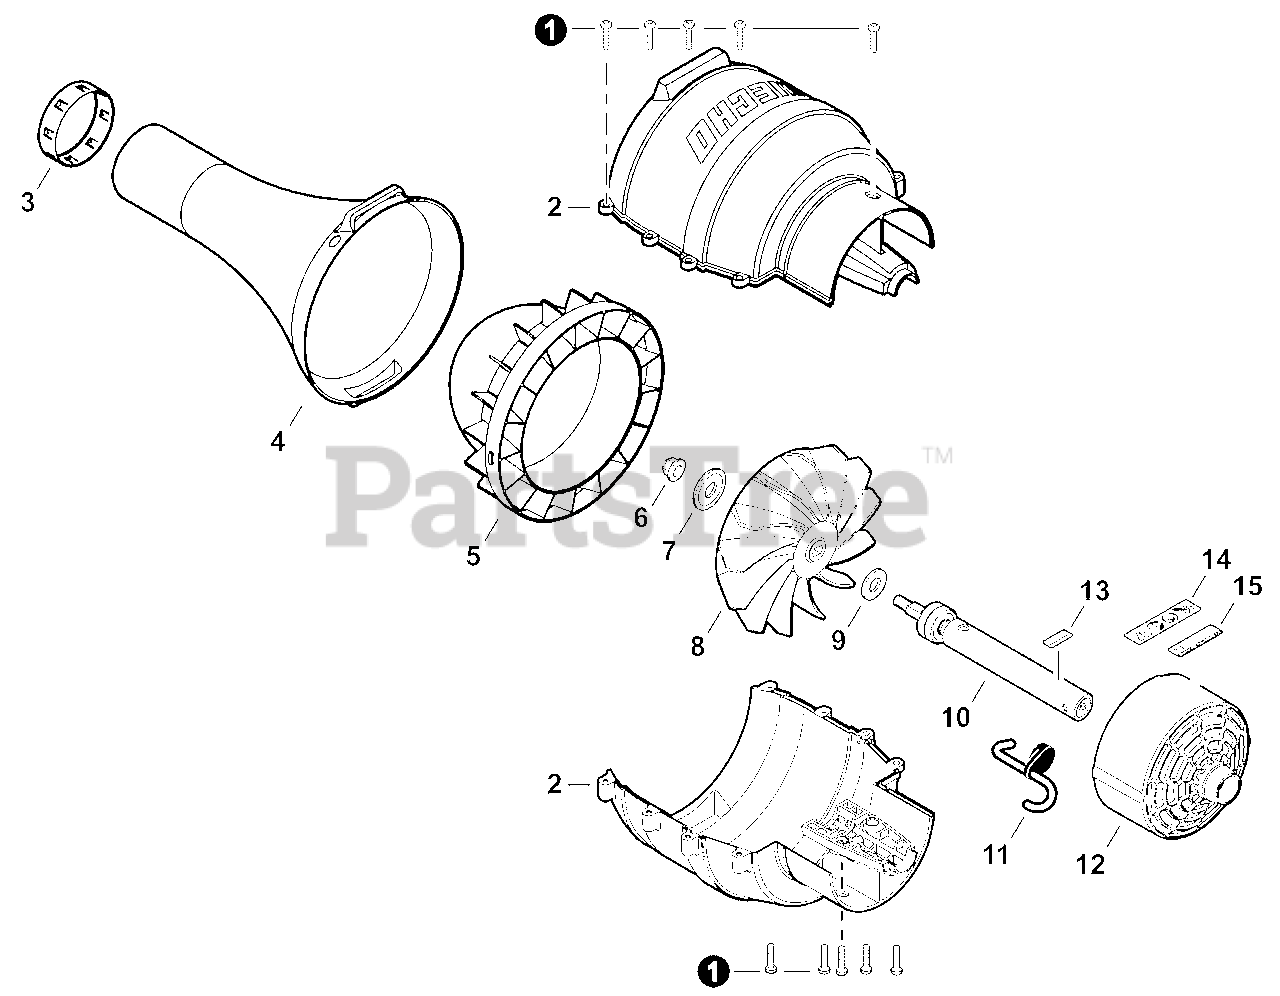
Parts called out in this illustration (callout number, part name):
1	BOLT, TORX 5×20
2	CASE, FAN
4	TUBE, BLOWER
5	GUIDE, AIR
6	NUT, FLANGE
7	WASHER 8.2×31×0.8
8	FAN, BLOWER
10	MAIN PIPE ASSY
11	HANGER, ATTACHMENT
12	SHIELD, DEBRIS
13	LABEL - ALIGNMENT
14	LABEL, CAUTION - ISO
15	LABEL, NOISE - 71DB(A) CAT. III
